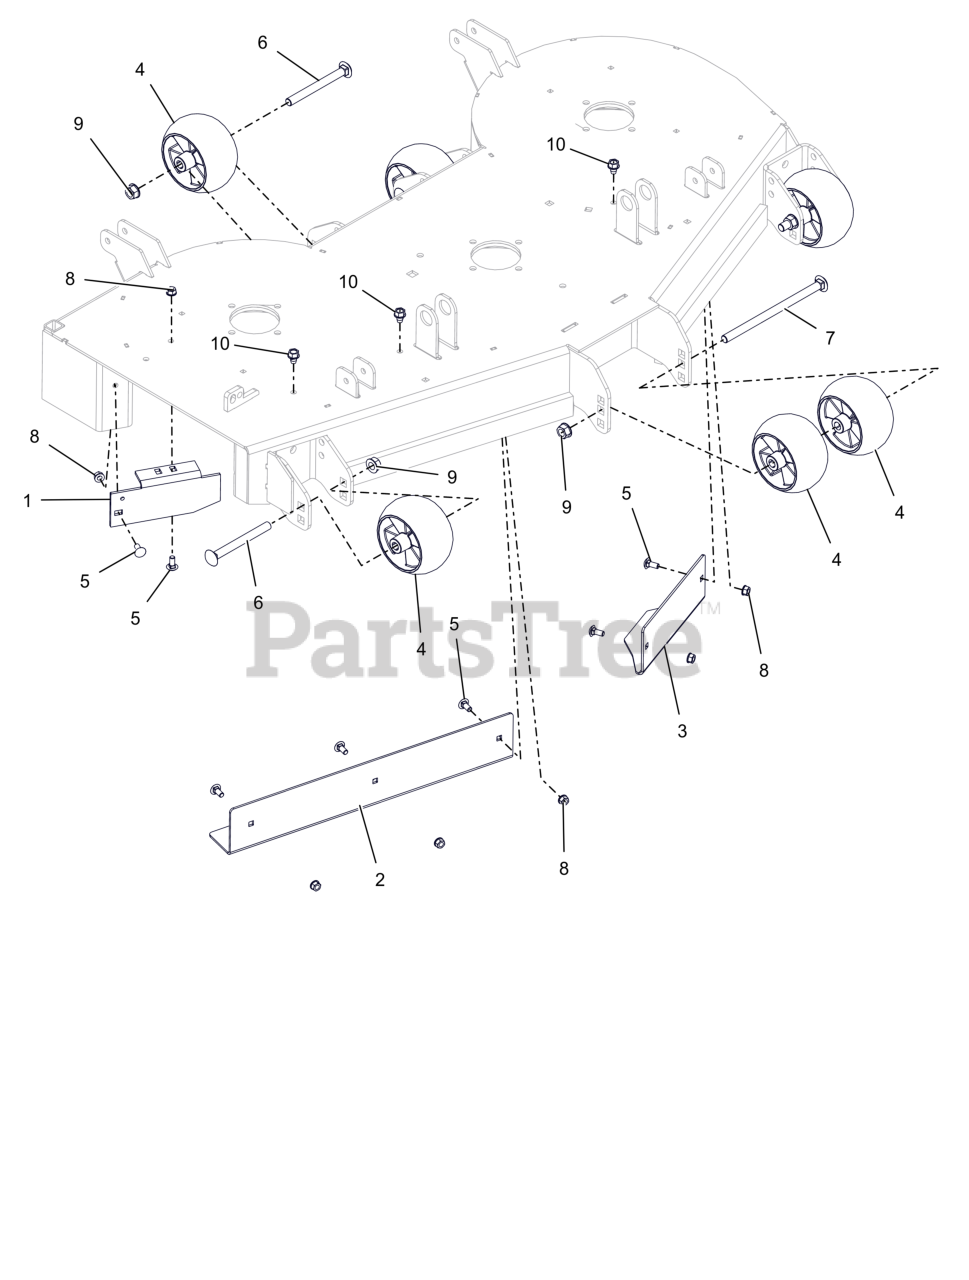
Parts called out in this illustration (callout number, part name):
1	44"-48" SIDE DISCH BAFFLE -RED
2	BAFFLE, 48" RH VACUUM (RED)
3	BAFFLE, 44/48" LH VACUUM (RED)
4	WHEEL, ANTI SCALP - 5X3 CTR W/RIBS
5	BLT,RHSN .31-18X.75 G5 ZCC
6	BLT, RHSN .50-13X5.00 G5 ZCC
7	BTL,RHSN .500-13 X 8.5S G5 ZCC
8	NUT,LK-CTR-FLG .31-18 GF ZCC
9	NUT-LK-CTR-FLG .500-13 GG ZCC
10	SCR,TAP .375-16X.50 HWH TR ZCC
